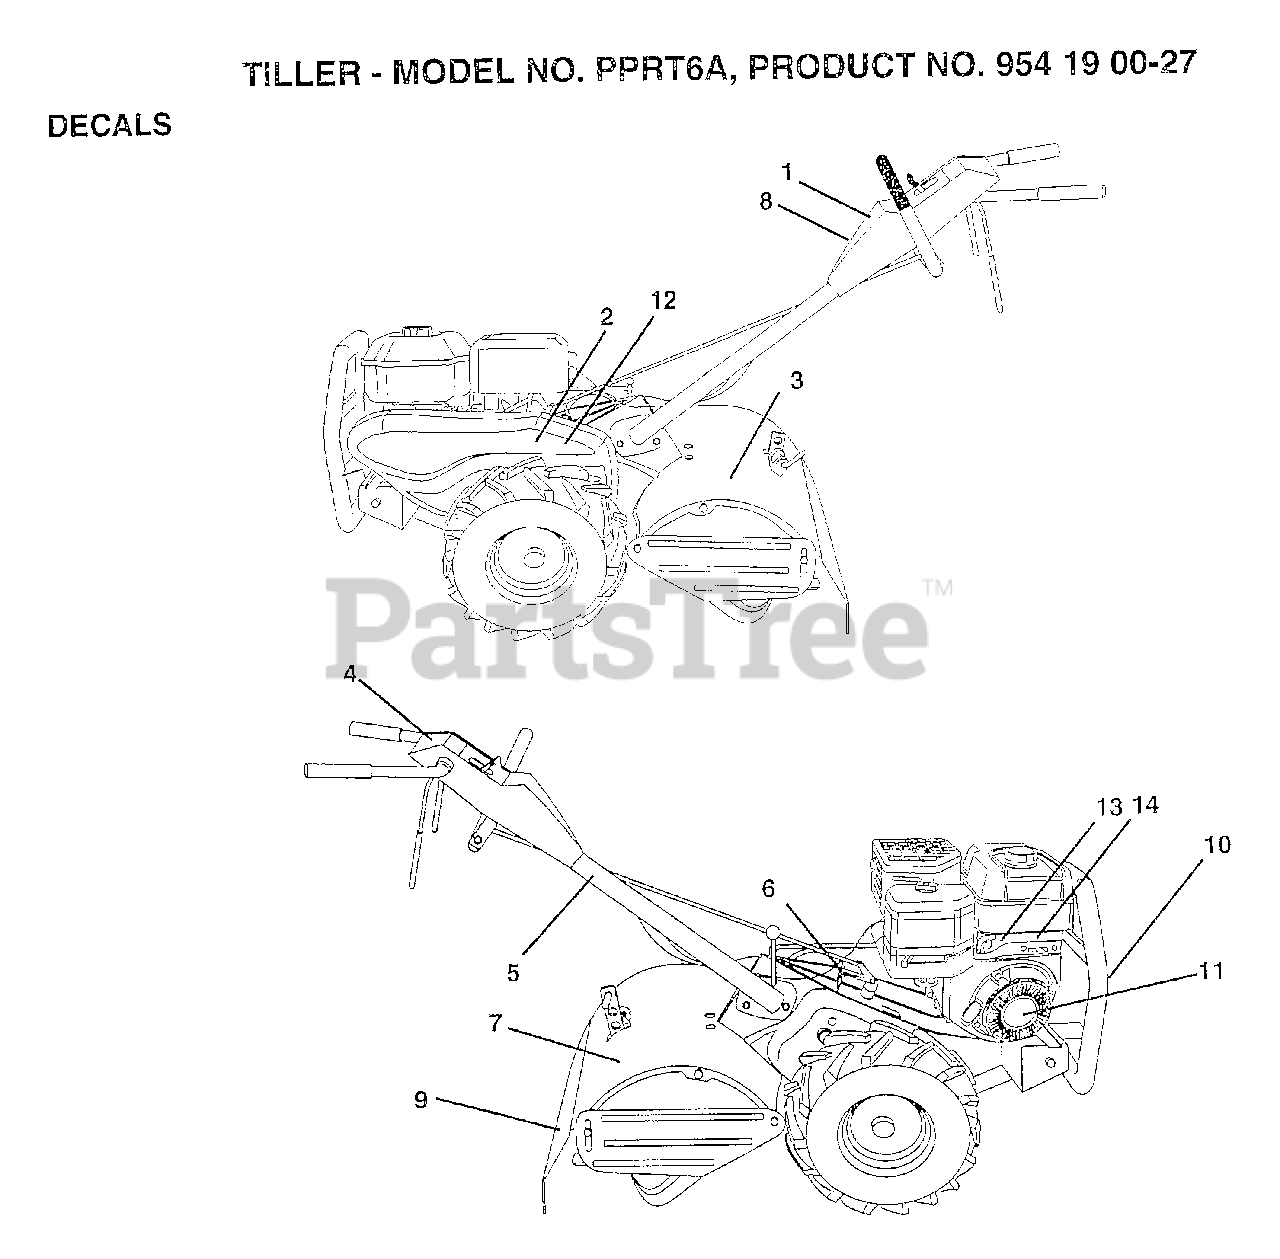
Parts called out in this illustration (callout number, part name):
1	DECAL, LOGO
2	DECAL, LOGO
3	DECAL, LOGO
4	DECAL.INSTRUCTION
5	DECAL TI
6	DECAL CRT
7	DECAL.CAUTION
8	DECAL, CONTROL PANEL
10	DECAL, BUMPER/GRILLE
12	RETAINER-SPRING
13	DECAL, CHOKE
